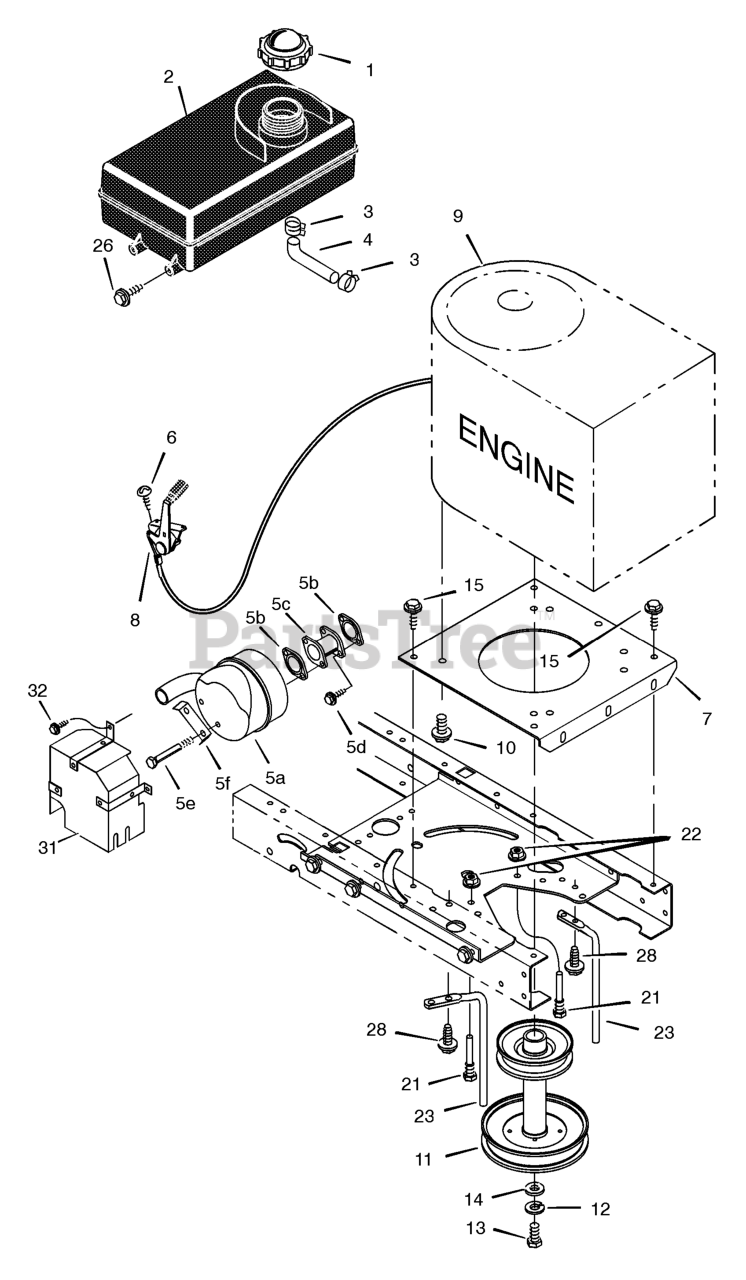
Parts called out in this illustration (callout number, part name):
1	Fuel Cap
2	TANK, Fuel 1.4 Gal.
3	Hose Clamp
4	Fuel Line (Must cut to length)
5A	Muffler
5B	GASKET, Exhaust
5C	Adapter, Muffler
5D	Screw, Adapter
5E	Bolt, Muffler
5F	Lock, Screw
7	Plate, Engine
8	Throttle Control
9	Engine *
10	Bolt, Engine Mount
11	Stack Pulley Assembly
12	Lockwasher
13	Bolt, Hex
21	Guide, Belt
22	Nut, Flange
23	Guide, Belt
28	Screw
31	Shield, Heat
